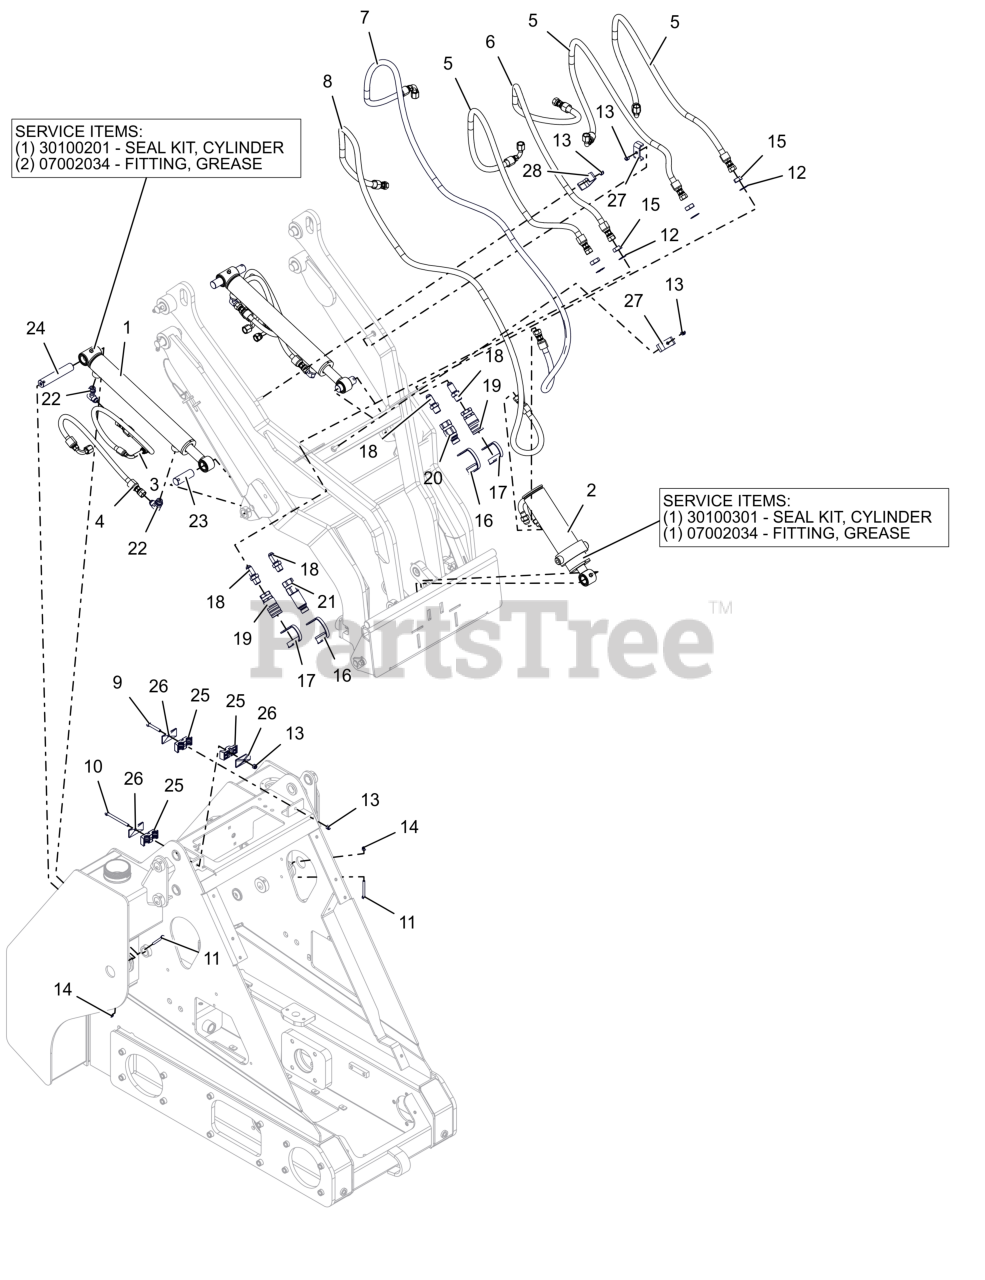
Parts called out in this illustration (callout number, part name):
1	CYLINDER, HYDRAULIC - LIFT
1	SEAL, KIT, CYLINDER
1	FITTING, GREASE
2	CYLINDER, TILT - W/SAFETY DECAL
2	SEAL, KIT, CYLINDER
2	FITTING, GREASE
3	HOSE, HYD .375" X 22.00" LG
4	HOSE, HYD .375" X 23.75" LG
5	HOSE, HYD .375" X 47.75" LG
6	HOSE, HYD .375" X 49.25" LG
7	HOSE, HYD .375" X 77.50" LG
8	HOSE, HYD .375" X
9	BLT, HEX .31-18X2.00 G5 ZCC
10	BLT, HEX .31-18X3.75 G5 ZCC
11	@BLT-HEX .25-20X2.50 GR5 YWZC
12	WSHR-LK-INT .750 YWZC
13	NUT,NYL .31-18 G5 ZCC
14	NUT,NYL .25-20 G5 ZCC
15	NUT-JAM .75-16 YWZC
16	CAP, HYD - DUST FFF
17	CAP, HYD - DUST FFM
18	FITTING, HYDRAULIC 2706 08-08
19	COUPLING, HYD -.50 NPTFFF
20	COUPLING, HYD -.50 NPTFFM
21	COUPLING, HYD -.50 NPT3FFM
22	FITTING, HYDRAULIC 6801 8-8
23	PIN, CYLINDER
24	PIN, CYLINDER
25	CLAMP, HOSE - TWIN .75"
26	PLATE, COVER - CLAMP
27	BRKT, RETAINING - HOSE SHORT (BLACK)
28	BRKT, RETAINING - HOSE TALL (BLACK)
